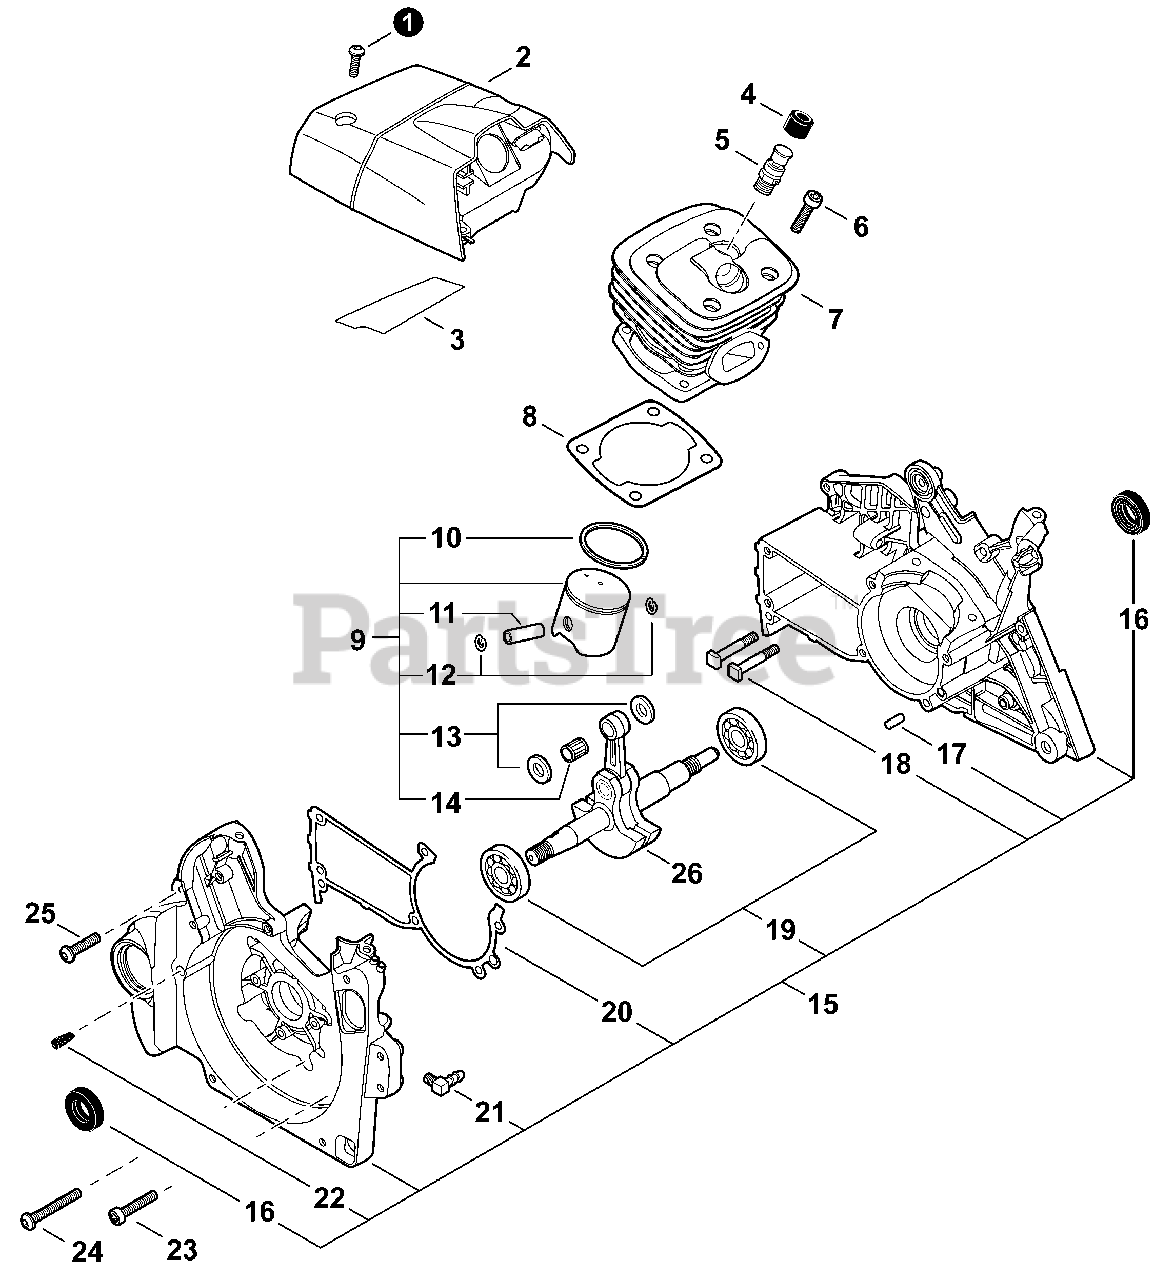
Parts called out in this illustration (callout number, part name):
1	BOLT, TORX 5×16
2	COVER, ENGINE
3	SHIELD, HEAT 75×32×0.15
4	COVER, DUST
5	VALVE ASSY, DECOMPRESSION
6	BOLT, TORX 5×25
7	CYLINDER
8	GASKET, CYLINDER
9	PISTON KIT
10	RING, PISTON
11	PIN, PISTON
12	RING, SNAP Ø11
13	WASHER, THRUST
14	BEARING, NEEDLE 11
15	CRANKCASE KIT
16	SEAL, OIL 15
17	PIN, LOCATING 5×10
18	BOLT, STUD M8×1.25×34.5
19	BEARING, BALL 6202
20	GASKET, CRANKCASE
21	CONNECTOR, PIPE
22	VENT ASSY
23	BOLT, TORX 5×25
24	BOLT, TORX 5×35
25	BOLT, TORX 5×20
26	CRANKSHAFT ASSY
